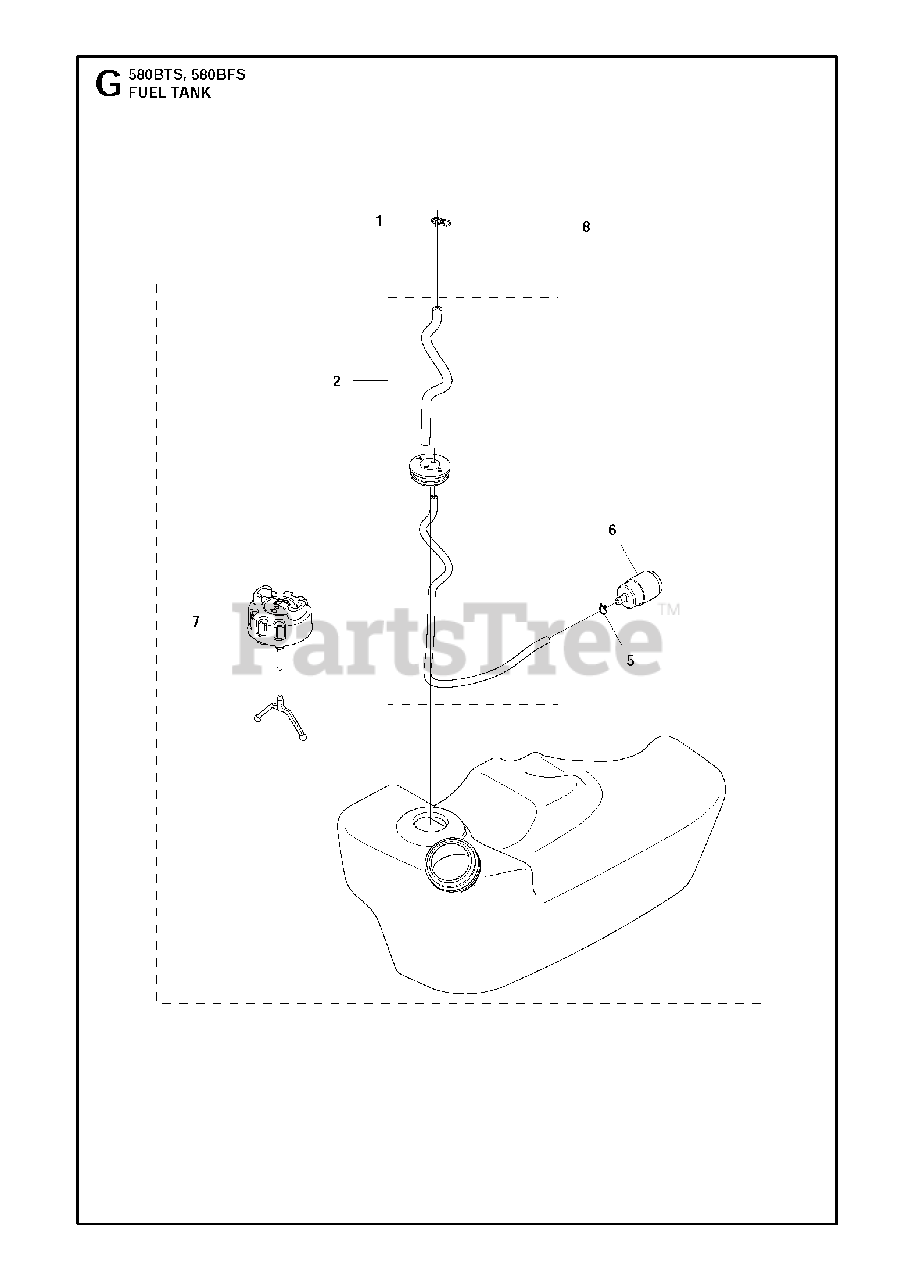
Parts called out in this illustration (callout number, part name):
2	PIPE
5	CLIP
6	FILTER ASSY
7	FUEL CAP ASSY
8	TANK ASSY
